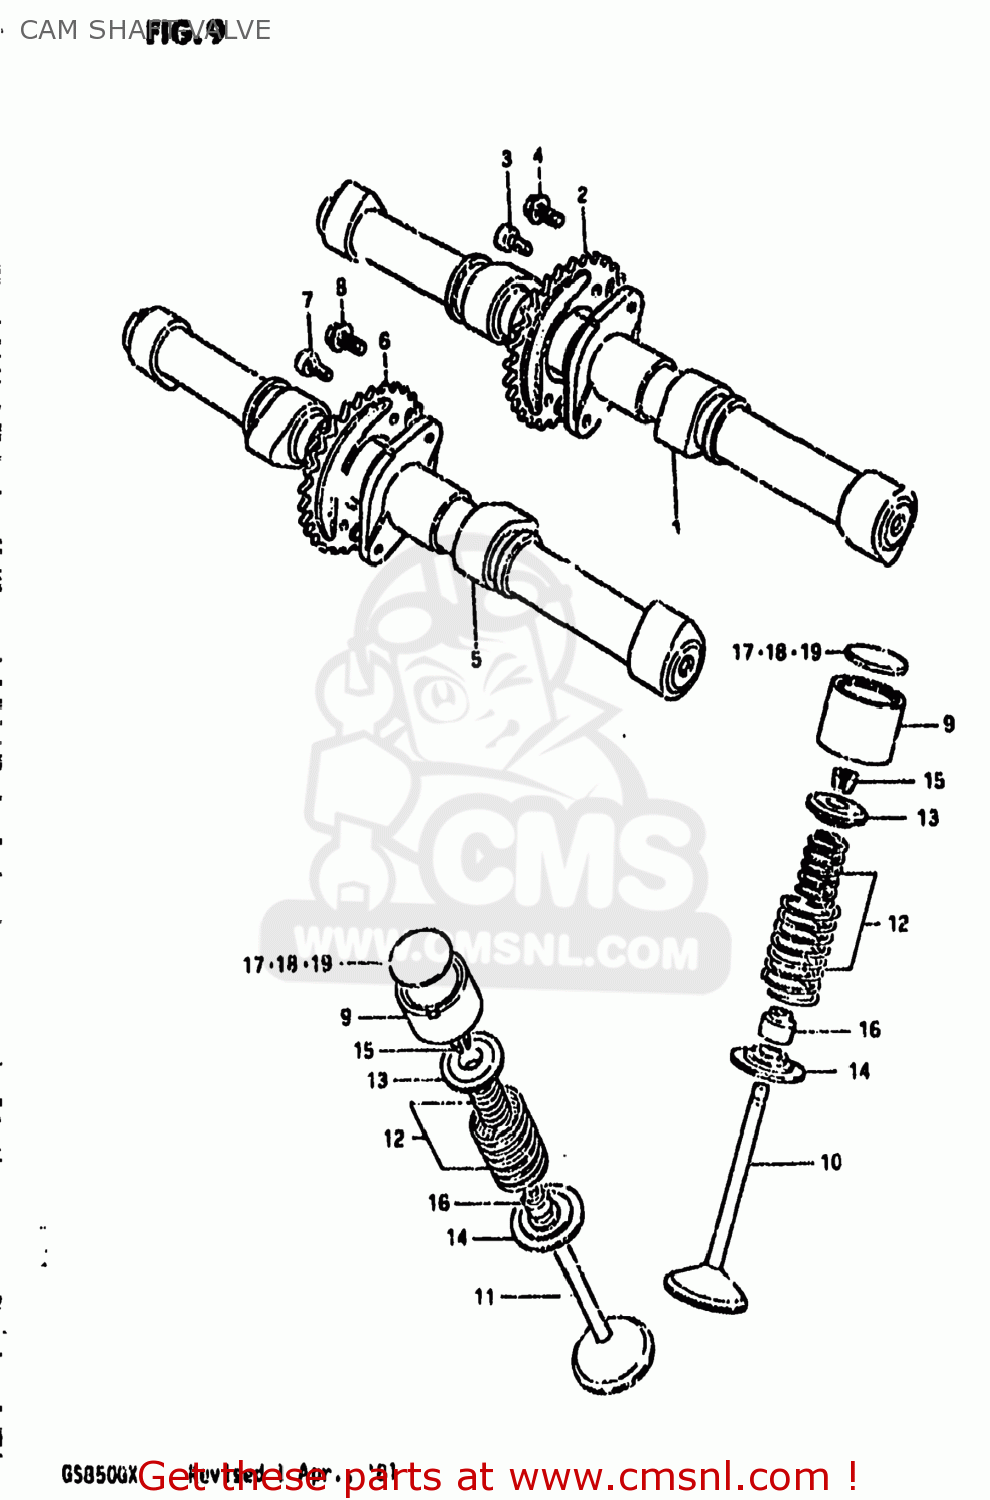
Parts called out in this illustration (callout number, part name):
1	CAMSHAFT
2	SPROCKET,CAMSHAFT
3	BOLT 6X11
4	BOLT(7X11)
5	CAMSHAFT,EXHAUST
6	SPROCKET,EXHAUST CAMSHAFT
7	BOLT 6X11
8	BOLT(7X11)
9	TAPPET
10	VALVE,INTAKE
11	VALVE,EXHAUST
12	SPRING SET,VALVE
13	RETAINER,VALVE SPRING
14	SEAT,VALVE SPRING
15	COTTER VALVE
16	SEAL,OIL(7X14.4X9)
17	SHIM,TAPPET
18	SHIM,TAPPET
19	SHIM,TAPPET
20	SHIM SET,TAPPET
21	CASE
